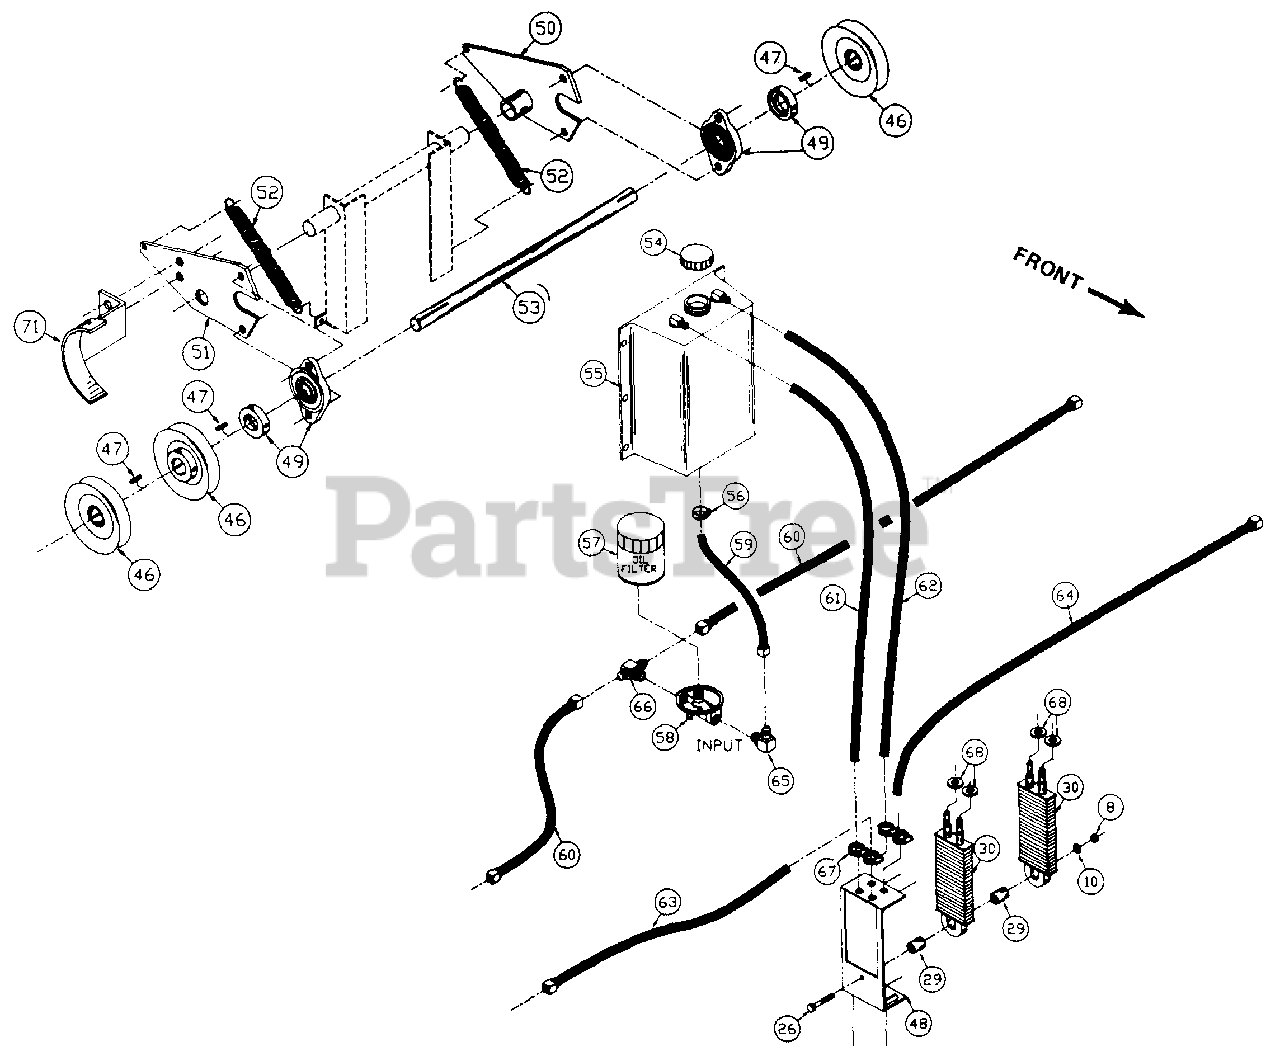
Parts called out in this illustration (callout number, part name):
8	Elastic Stop Nut, 1/4-20
10	Flatwasher, 1/4"
26	Hex Bolt, 1/4-20 x 2 1/4", GR5
29	Rubber Bushing
46	Pulley, 4" x 3/4" ID
47	Key, 3/16" x 3/16" x 1"
48	Oil Cooler Mount
49	Bearing, 2-Bolt Flanged
50	Cross Shaft Bearing Mount, LH
51	Cross Shaft Bearing Mount, RH
52	Ext. Spring, 1" x 7 1/4", 11 GA
53	Drive Cross Shaft
55	Oil Tank, SA
56	Hose Clamp, 5/8"
57	Filter Element
58	Filter Head, #6 Ports
59	Hose Assembly, 5/8" x 11"
60	Hose Assembly, 3/8" x 13"
61	Hose, 3/8" x 25"
62	Hose, 3/8" x 27"
63	Hose Assembly, 3/8" x 38"
64	Hose Assembly, 3/8" x 24"
65	Male Tube, 90° Male O-ring Adpt.
66	Male O-ring, Male Tube Tee
67	Hose Clamp, 3/8"
68	Grommet, 1/2" ID x 1" OD
71	Cross Shaft Belt Retainer
